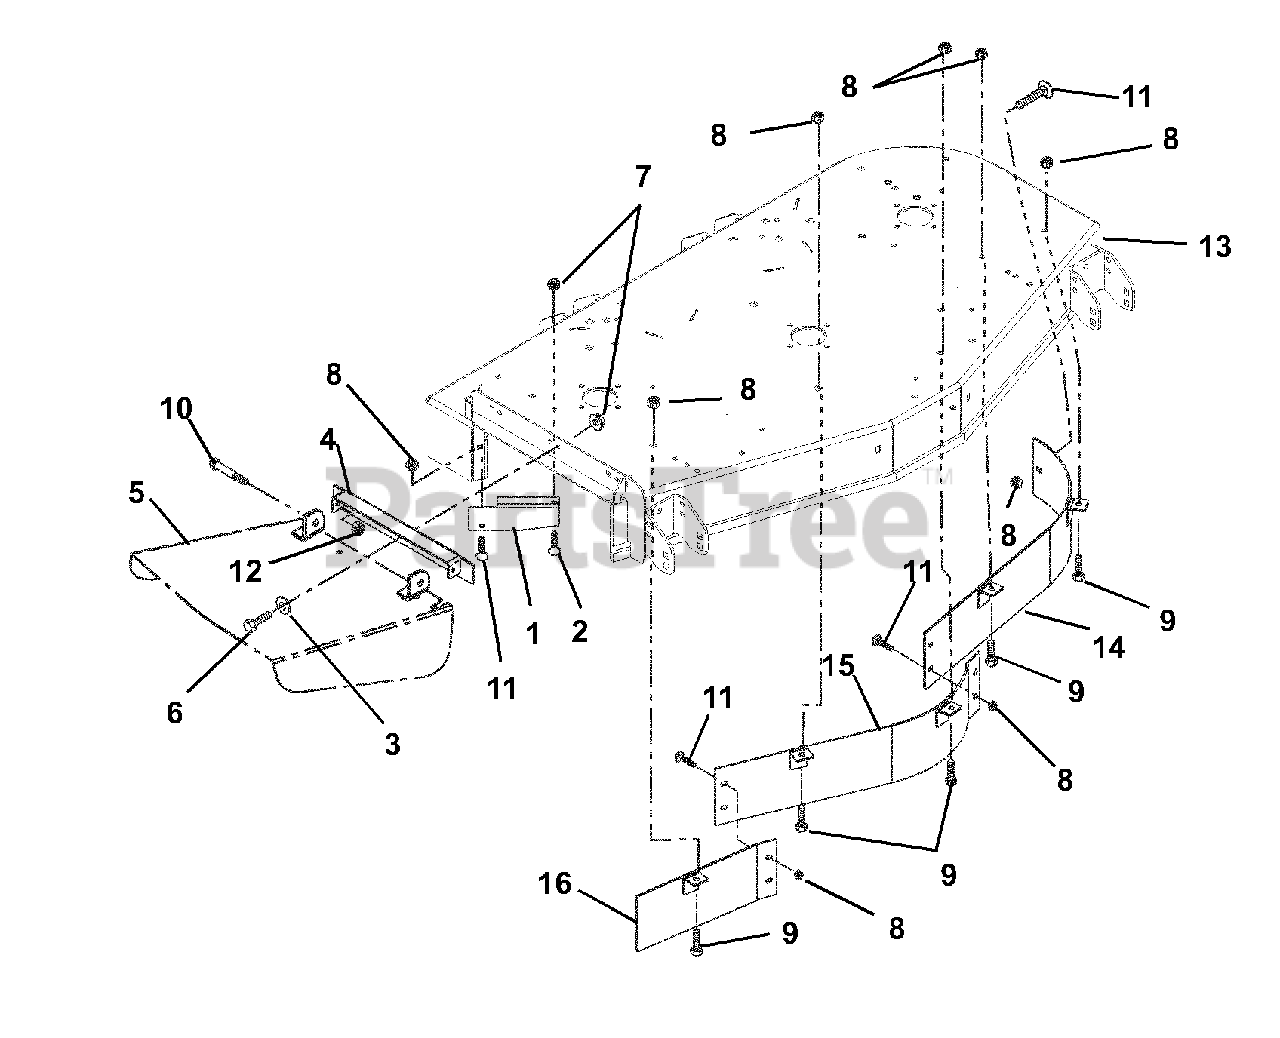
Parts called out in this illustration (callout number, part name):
1	Deflector, 52" (079, 081)
1	Deflector, 60" (080, 082)
1	Deflector, 44" (064, 077, 078, 083, 310, 311)
2	Bolt, Round Head Square Neck .38-16 x 1.00 Grade 5
3	Washer, Flat Steel .38 x .875 x .083 (064, 077, 078, 079, 081, 083, 310, 311)
4	Weldment Discharge Chute Bracket (064, 077, 078, 079, 081, 083, 310, 311)
4	Weldment Discharge Chute Bracket (080, 082)
5	Chute, Discharge (310, 311)
5	Chute, Discharge (080, 082)
5	Chute, Discharge (064, 077, 078, 079, 081, 083)
6	Bolt, Hex .38-16 x 1.00 Grade 5
7	Nut, Locking Top Flange .38-16
8	Nut, Locking Top Flange .31-18
9	Bolt, Hex .31-18 x .75 Grade 5
10	Bolt, Shoulder .38-16 x .50 Socket Head
11	Bolt, Round Head Square Neck .31-18 x .75 Grade 5
12	Nut, Locking Center .38-16
13	Weldment, 52" Mower Deck (079, 081)
13	Weldment, 60" Mower Deck (080, 082)
13	Weldment, 44" Mower Deck Float (064, 077, 083, 310)
13	Weldment, 48" Mower Deck (078, 311)
14	Baffle, Left Front - 52" (079, 081)
14	Baffle, Left Front - 60" (080, 082)
14	Baffle, Left Front - 44" (064, 077, 083, 310)
14	Baffle, Left Front - 48" (078, 311)
15	Weldment, Baffle Center Front - 52" (079, 081)
15	Weldment, Baffle Center Front - 60" (080, 082)
15	Weldment, Baffle Center Front - 44" (064, 077, 083, 310)
15	Weldment, Baffle Center Front - 48" (078, 311)
16	Weldment, Baffle Right Front - 52" (079, 081)
16	Weldment, Baffle Right Front - 60" (080, 082)
16	Weldment, Baffle Right Front - 44" (064, 077, 083, 310)
16	Weldment, Upper Baffle Right - 48" (078, 311)
